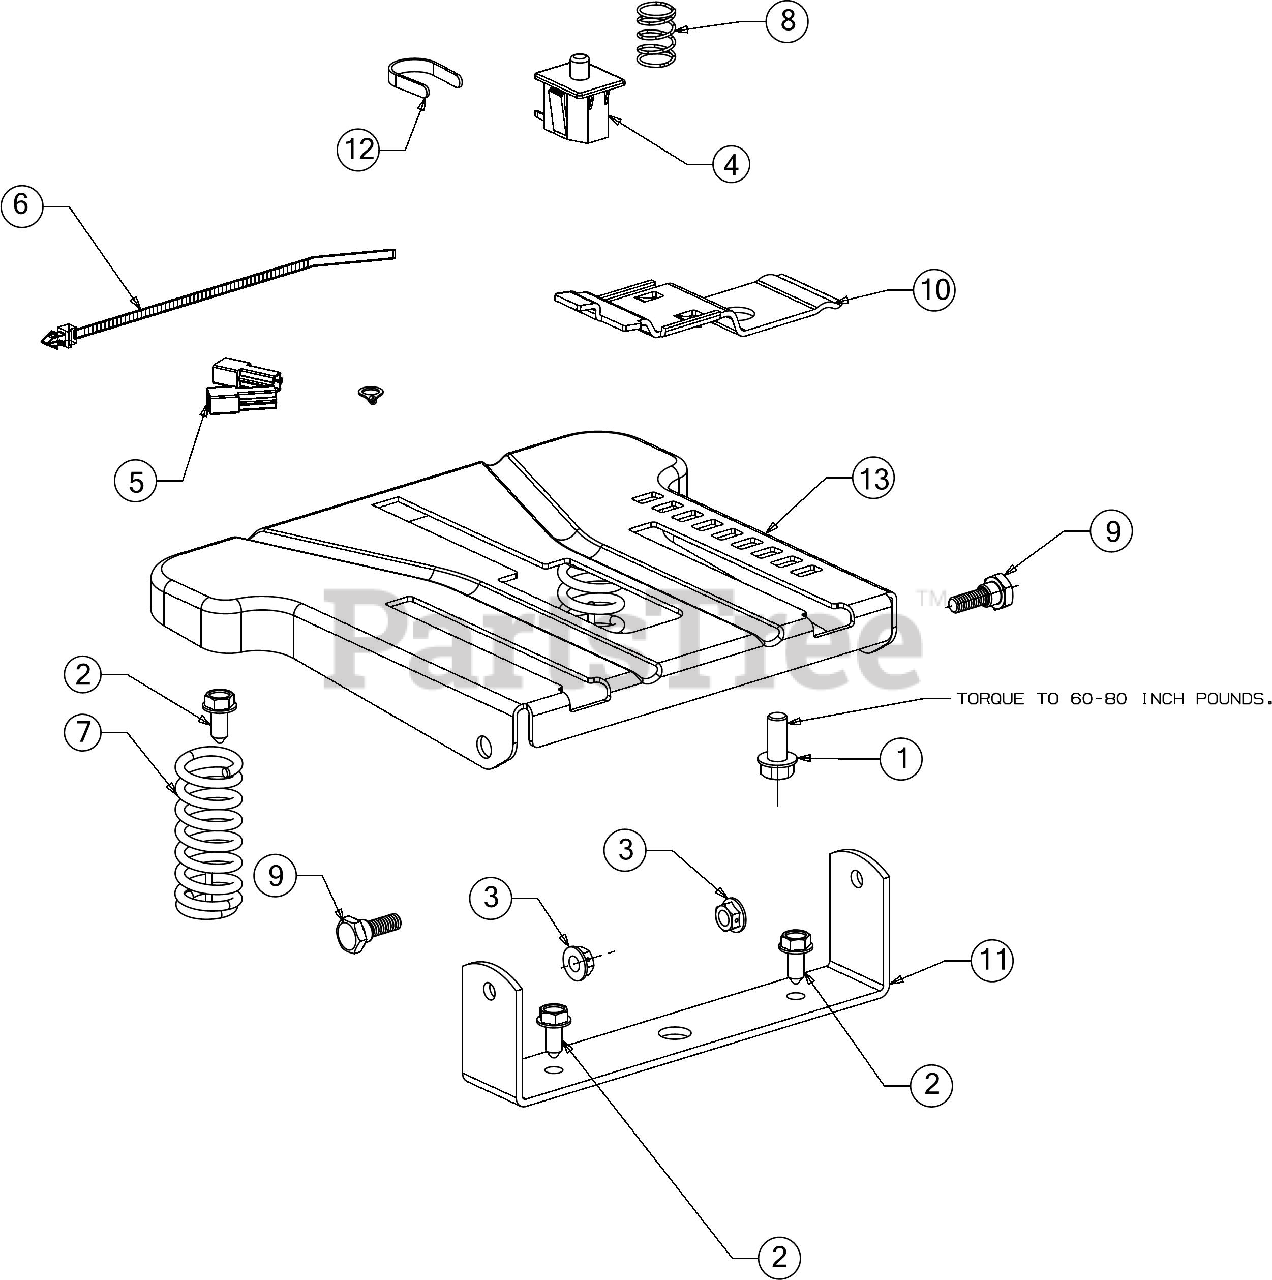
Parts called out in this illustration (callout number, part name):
1	SCREW 3/8-16 X .875 GR5
2	SCREW 5/16-18 X .750
3	HEX FLANGE NUT
4	SEAT SWITCH
5	HARNESS
6	PUSH MOUNT TIE
7	COMPRESSION SPRING
8	COMPRESSION SPRING
9	SHOULDER SCREW .437
10	SEAT ADJUST LEVER
11	SEAT PIVOT BRACKET
12	RETAINING CLIP
13	SEAT MOUNT BRACKET
